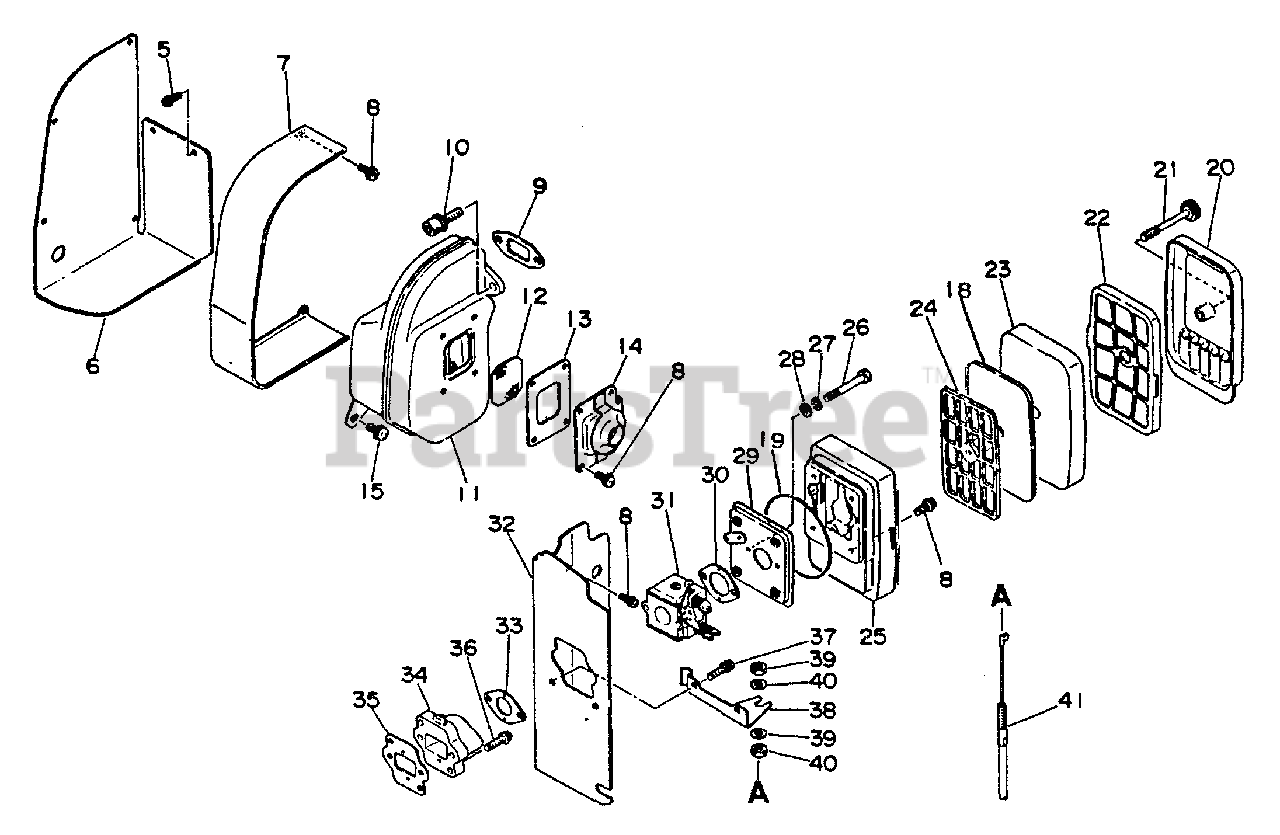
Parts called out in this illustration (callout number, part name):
5	SCREW 4×14
6	INSULATOR
7	COVER, MUFFLER
8	SCREW 4×10
9	GASKET, EXHAUST
10	BOLT 6×20
11	MUFFLER
12	SCREEN, SPARK ARRESTER
13	GASKET
14	GUIDE, EXHAUST
15	BOLT 5×16
18	FILTER, AIR
19	GASKET
20	COVER, AIR FILTER
21	WINGNUT
22	HOLDER, AIR FILTER
23	FILTER, AIR
24	RETAINER, AIR FILTER
25	CASE, AIR FILTER
26	BOLT
27	WASHER, SPRING 5
28	WASHER, FLAT 5.5×10×0.8
29	BRACKET
30	GASKET, INTAKE
31	CARBURETOR
32	INSULATOR
33	GASKET, INTAKE
34	INSULATOR, INTAKE
35	GASKET, INTAKE
36	SCREW 5×25
37	SCREW 5×20
41	CABLE, THROTTLE
